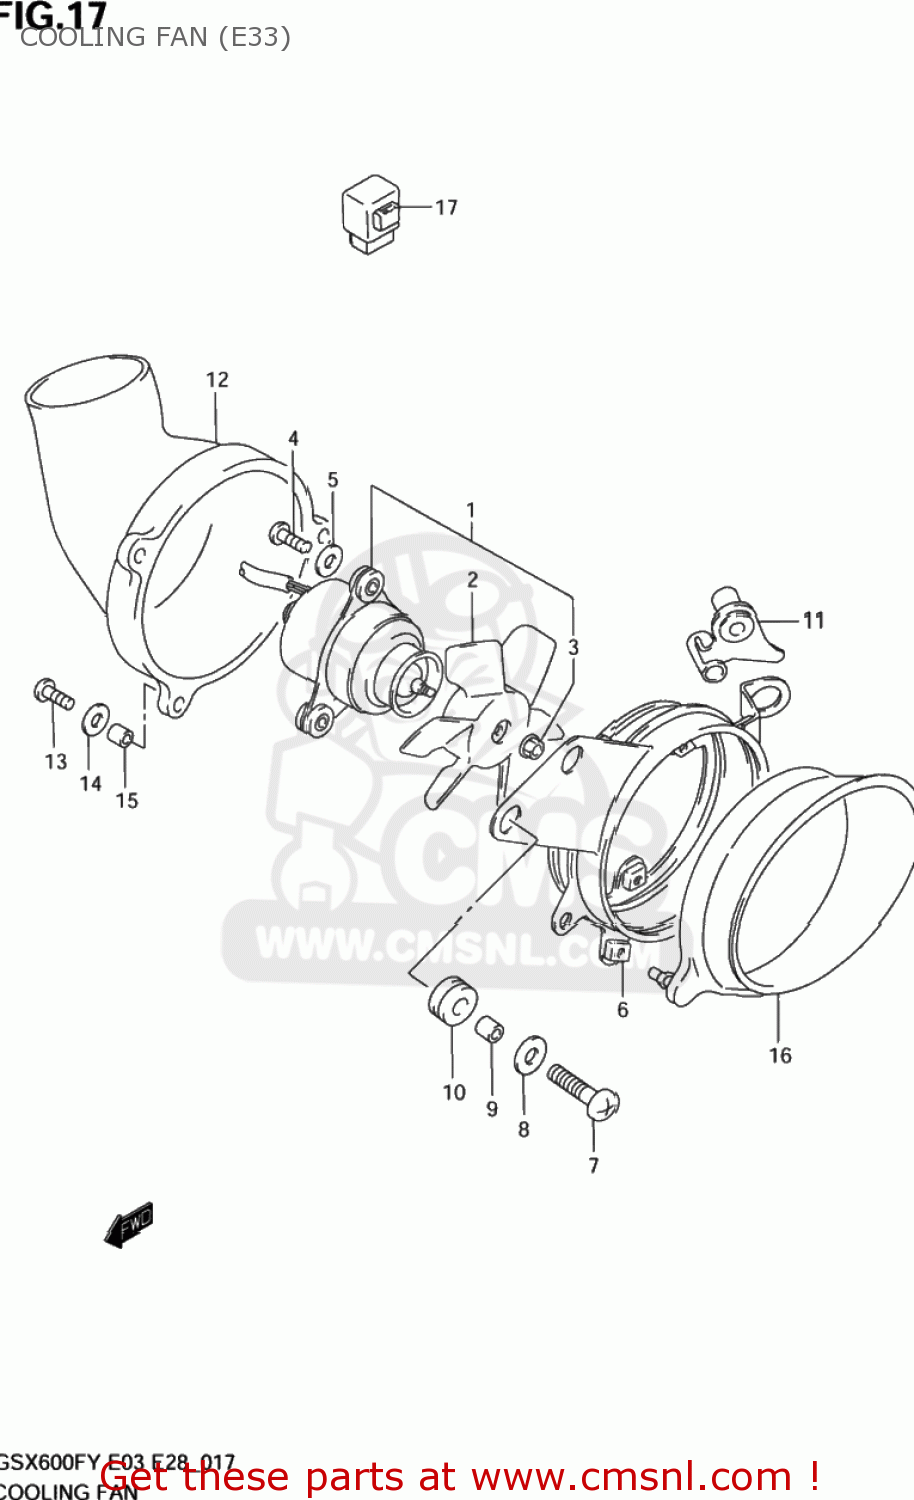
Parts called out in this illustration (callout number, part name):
1	FAN ASSY,COOLING
2	FAN
3	NUT
4	SCREW 4X16
5	WASHER(4.3X14X0.8)
6	SHROUD,FAN
7	SCREW
8	WASHER(6.5X18X1)
9	SPACER(6.5X9X6.5)
10	CUSHION
11	BRACKET,FAN SHROUD
12	DUCT,FAN COOLING NO.1
13	SCREW
14	WASHER(4.3X14X0.8)
15	SPACER(4.5X6.5X5)
16	DUCT,FAN COOLING NO.2
17	CONTROLLER ASSY,FAN MOTOR
